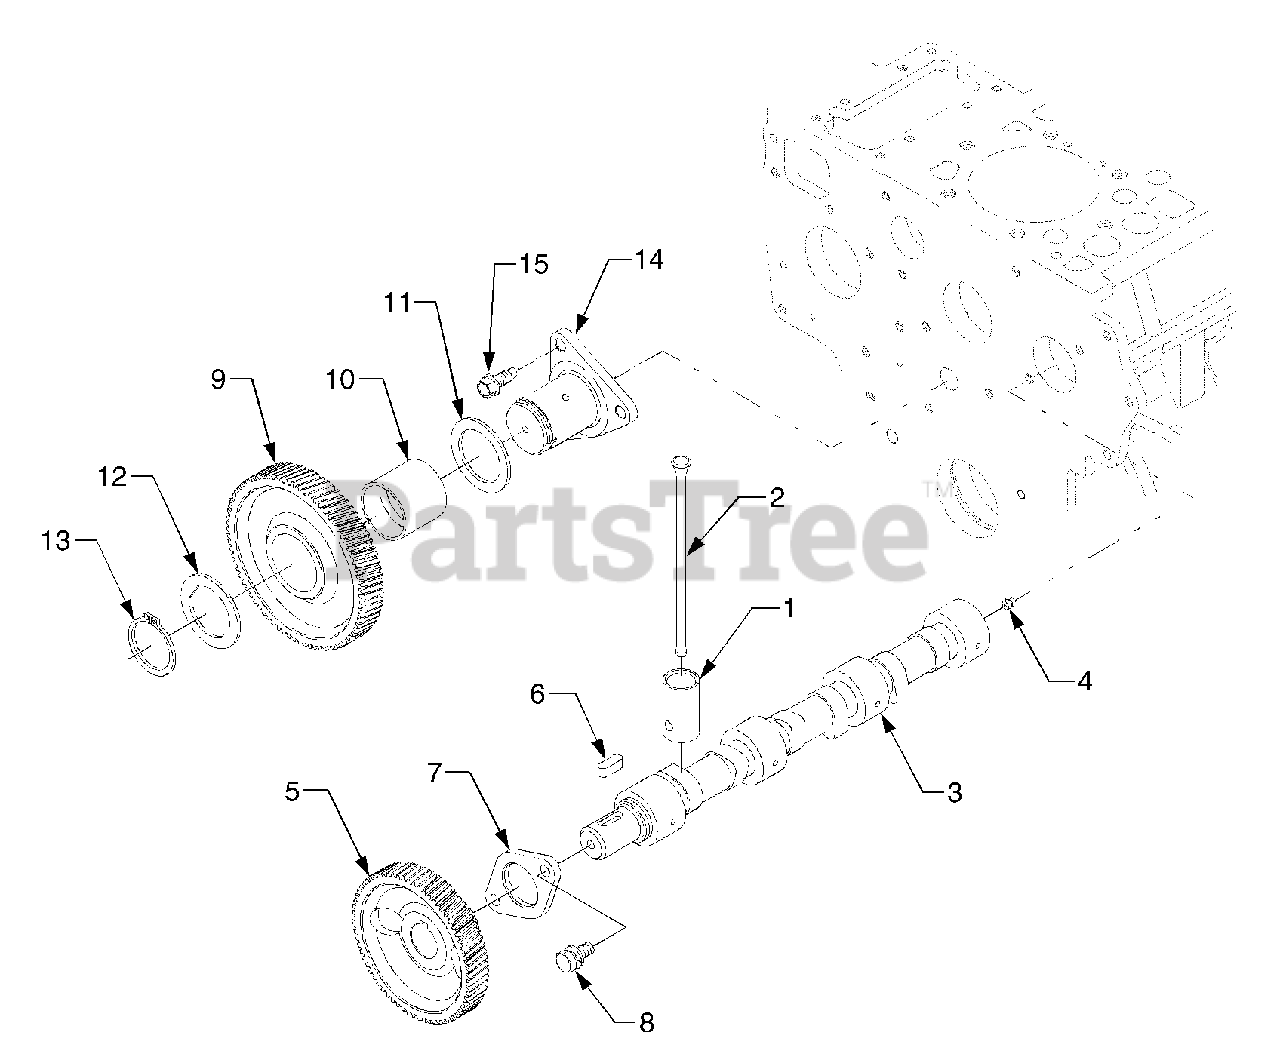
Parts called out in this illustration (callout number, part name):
2	Rod, Push
3	Camshaft Ass'y
5	Gear, Camshaft
7	Stopper, Camshaft
9	Idle Gear Ass'y
10	Bush, Idle Gear
14	Shaft, Idle Gear
